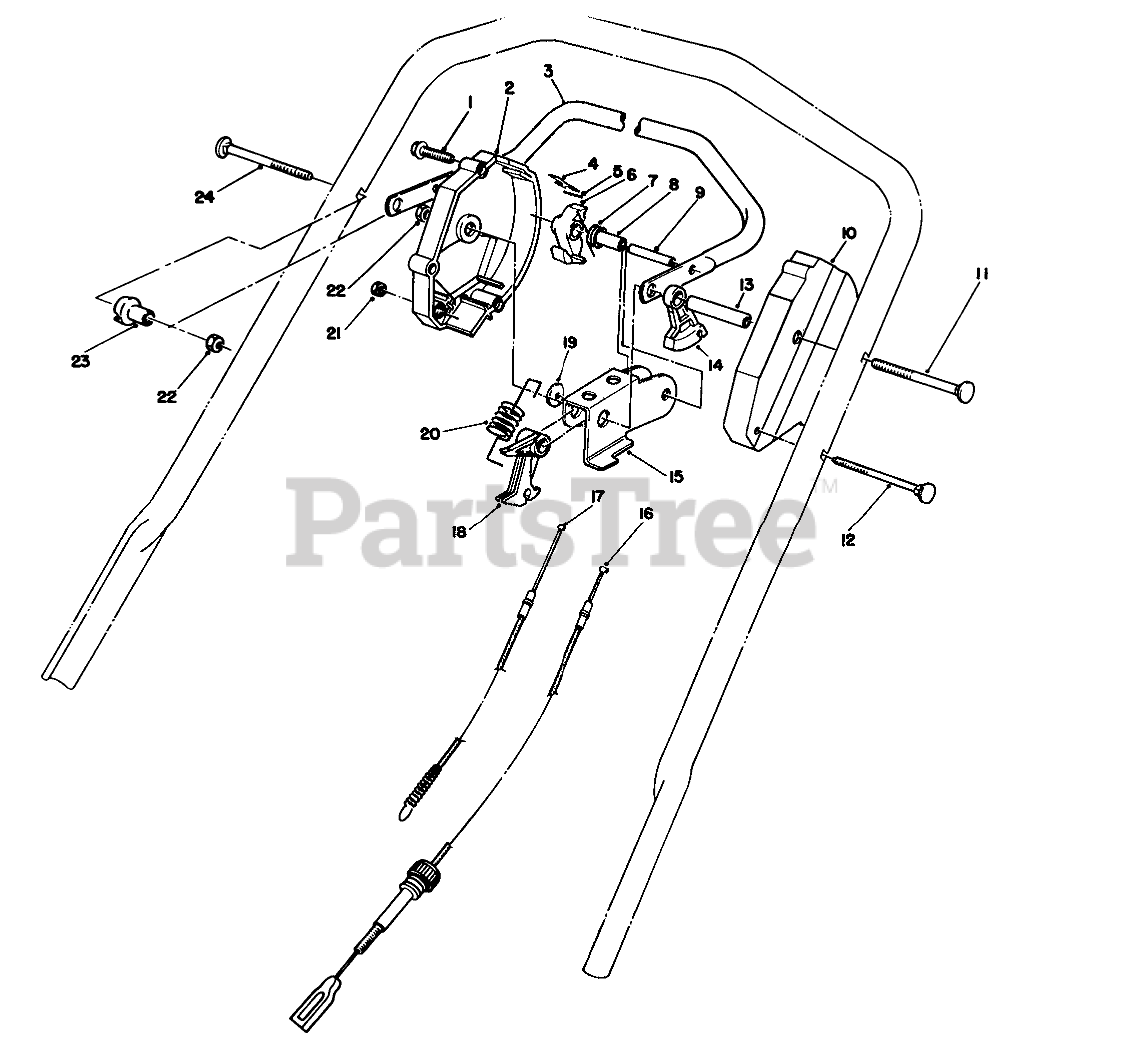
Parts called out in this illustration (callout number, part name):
1	SCREW-HWHTF
2	Housing-Control R.H. (Incl Ref. #4 & 5)
3	Bar-Control
4	SPRING-LEAF
5	PIN-INSERT
6	HOOK-CONTROL
7	SPRING-TORSION
8	SPACER
9	PIN-ROLL, SLOTTED
10	HOUSING-CONTROL, LH
11	5/16-18 X 3 HNDLE SCREW
12	HANDLE SCREW
13	TUBING-SPACER
14	LEVER-TRACTION
15	ROCKER
16	TRACTION CABLE
17	Cable-Clutch
18	LEVER-CABLE
19	WASHER-NYLON
20	SPRING-DETENT
21	NUT-HEX
22	NUT-LOCK, NI
23	SPACER-SUPPORT
24	5/16-18 X 2 HNDLE SCREW
